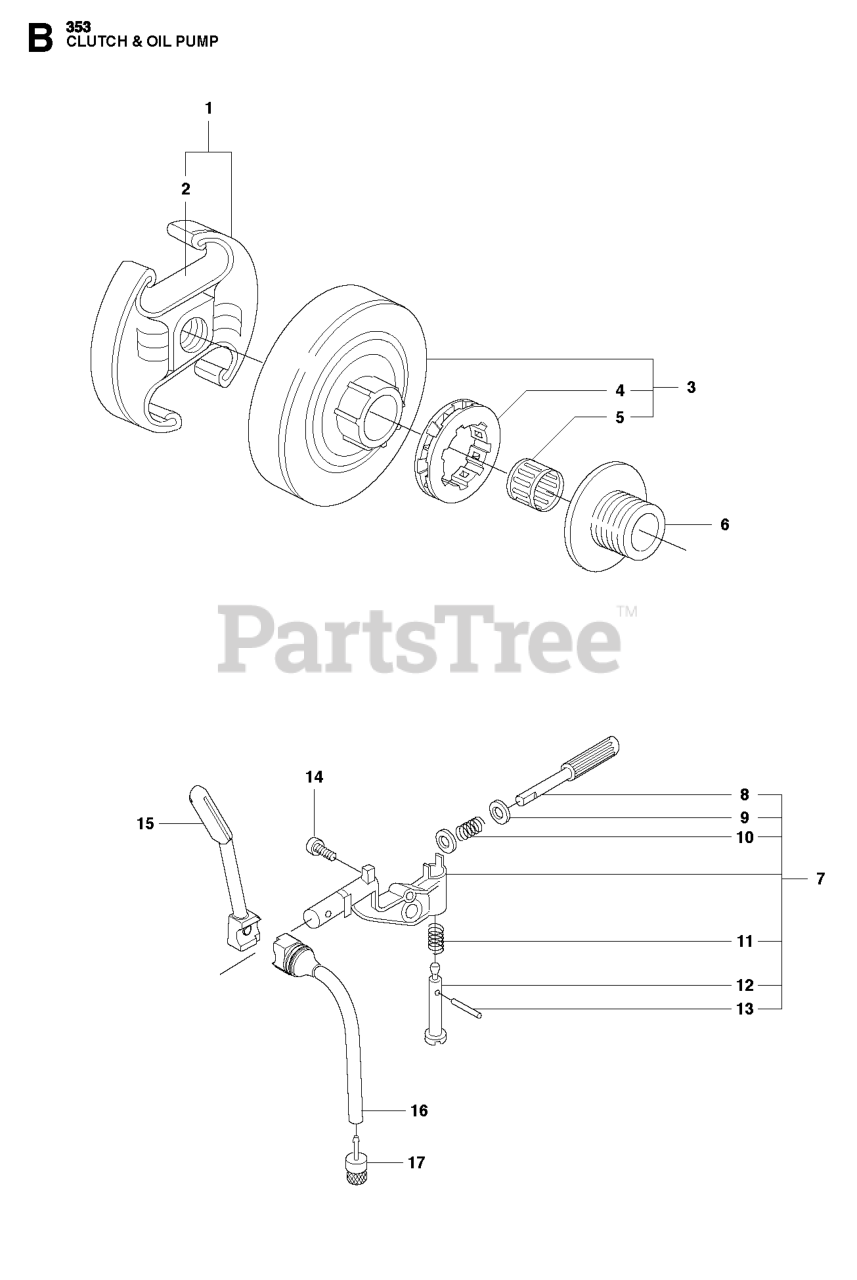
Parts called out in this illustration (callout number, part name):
3	CLUTCH DRUM
3	CLUTCH DRUM 3/8
4	RIM SPROCKET 7T .325
4	RIM SPROCKET 3/8'' 7
5	NEEDLE BEARING
6	PUMP PINION
7	OIL PUMP ASSY
8	PUMP PISTON
15	OIL PRESSURE HOSE
16	HOSE
17	OIL PLUMMET
